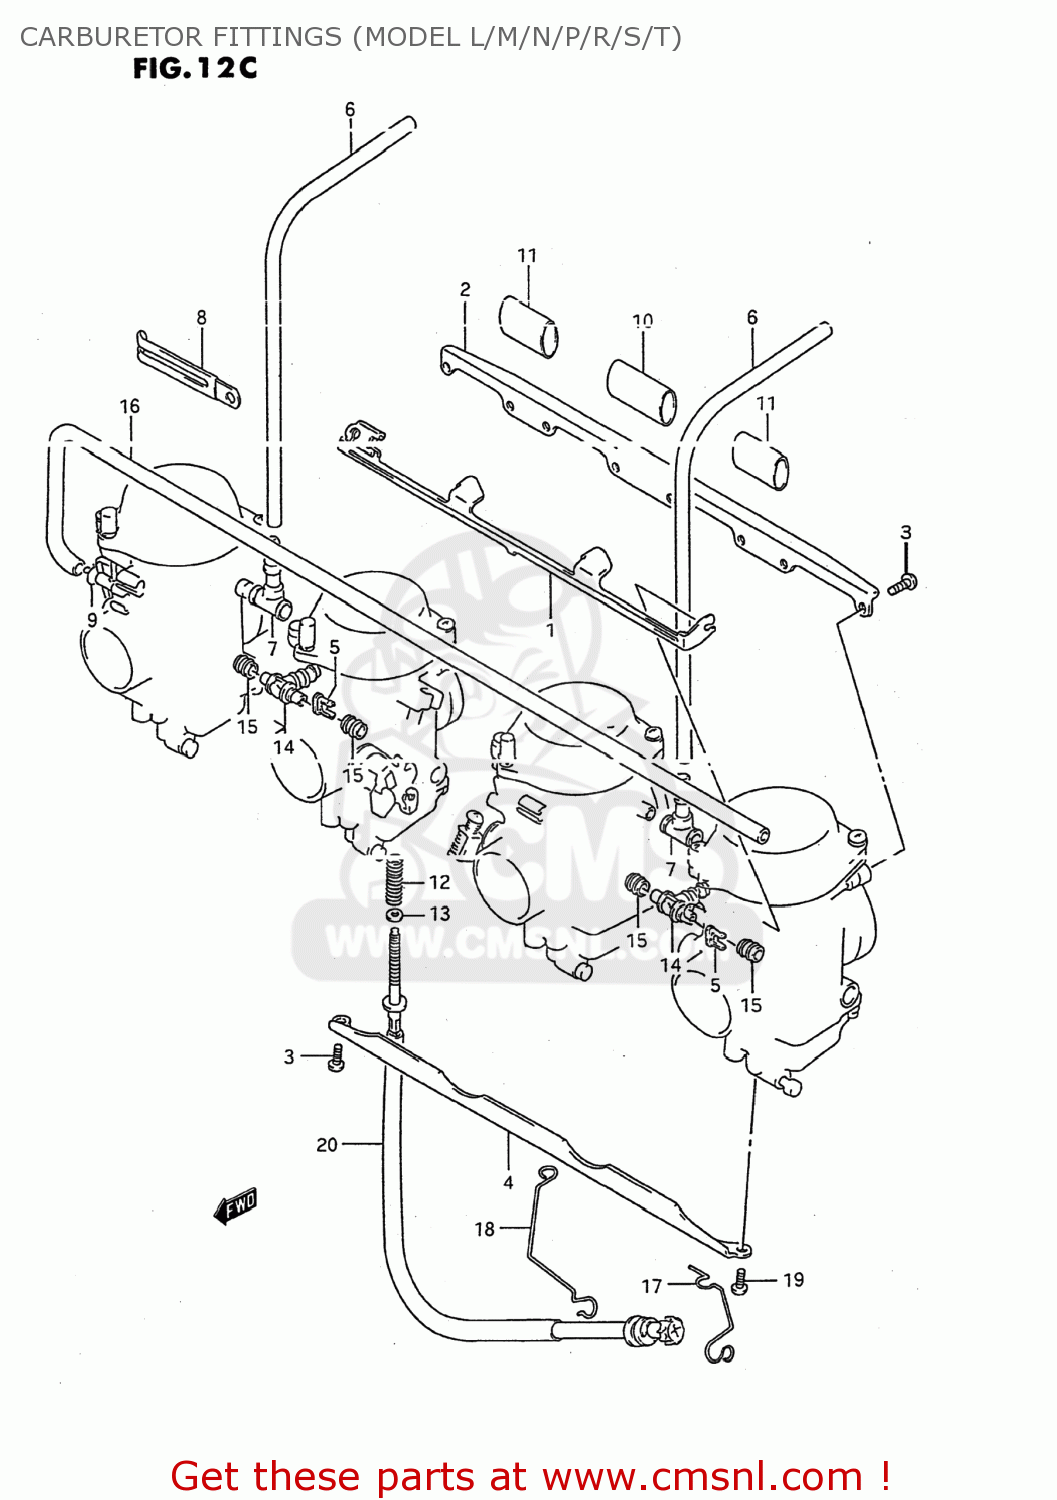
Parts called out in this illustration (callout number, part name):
1	LEVER
2	PLATE
3	SCREW
4	PLATE
5	HOLDER
6	HOSE(7X10.2X600)
7	HOSE
8	CLAMP(L:80)
9	CLIP
10	HOSE(16X19X100)
11	HOSE(16X19X100)
12	SPRING
13	WASHER
14	NIPPLE
15	SEAL
16	HOSE
17	CLIP
18	CLIP
19	SCREW(5X14)
20	ADJUSTER
